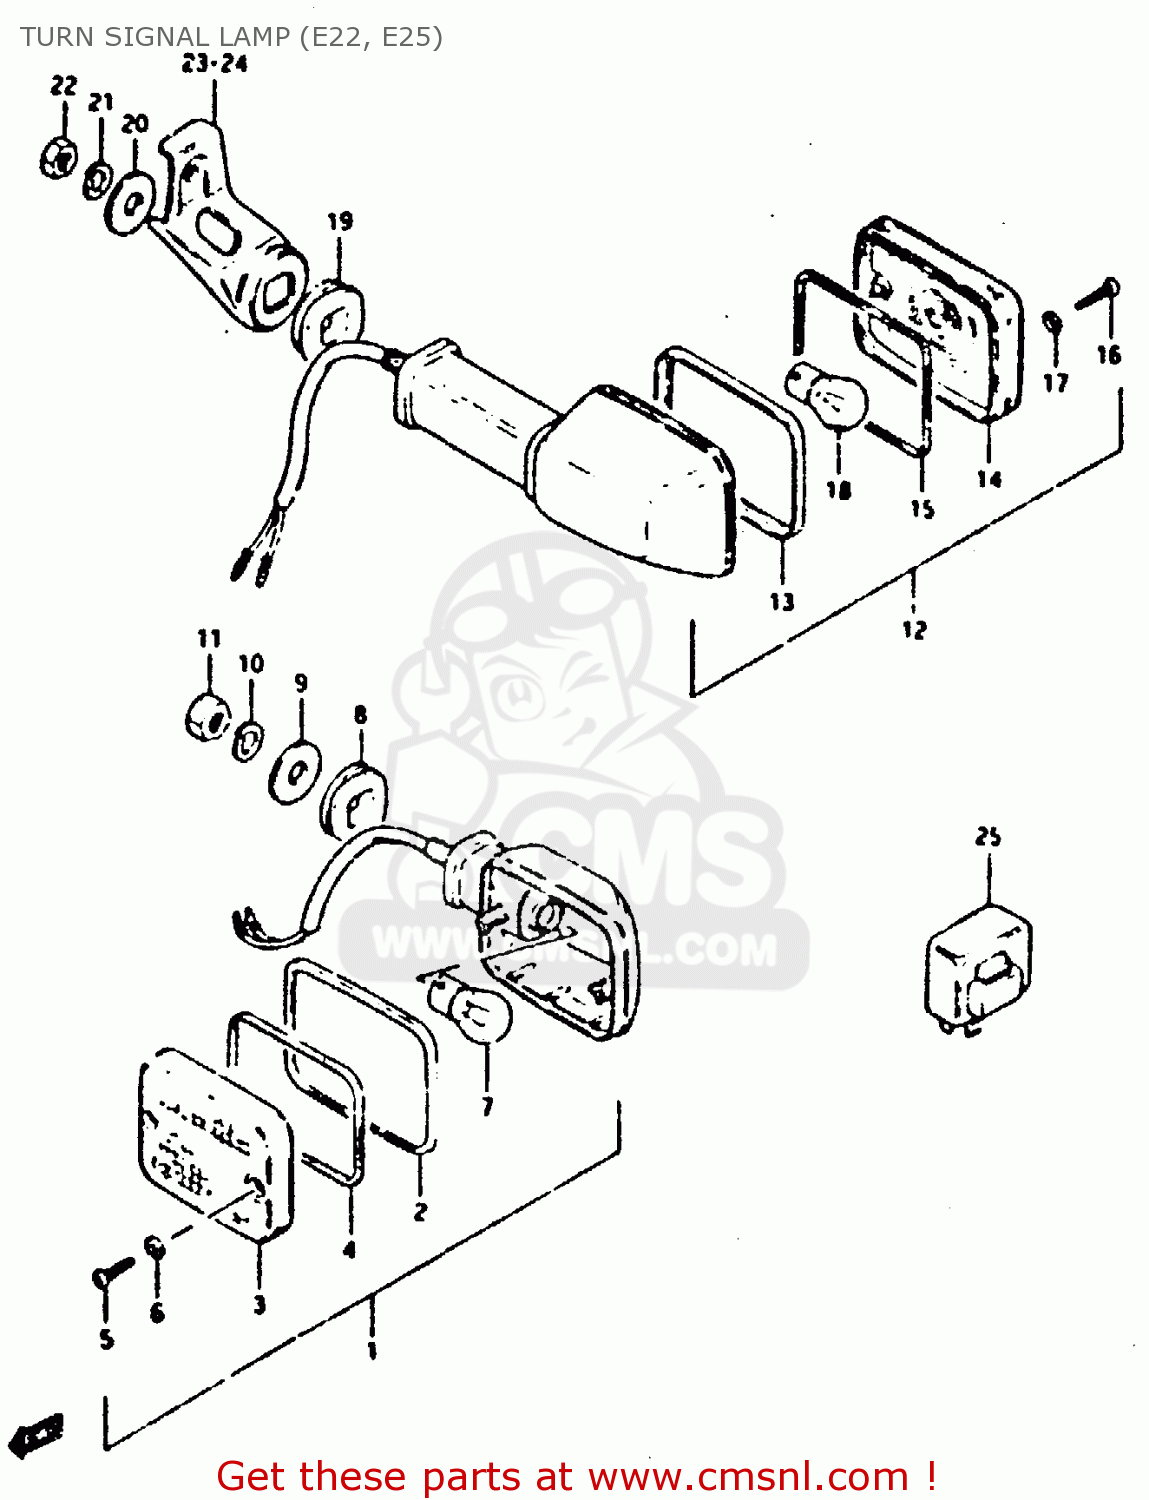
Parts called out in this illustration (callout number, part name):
1	LAMP, FRONT TURN SIGNAL
2	RIM
3	LENS
4	GASKET (NAS)
5	SCREW
6	GASKET (NAS)
7	BULB(12V21W)
8	CUSHION
9	WASHER (10.5X30X2.3)
10	LOCK WASHER
11	NUT
12	LAMP ASSY,RR T
13	RIM
14	LENS
15	GASKET (NAS)
16	SCREW
17	GASKET (NAS)
18	BULB(12V21W)
19	CUSHION
20	WASHER (10.5X30X2.3)
21	LOCK WASHER
22	NUT
23	BRACKET,REAR TURN SIGNAL
24	BRACKET,REAR TURN SIGNAL
25	RELAY, TURN SIGNAL
